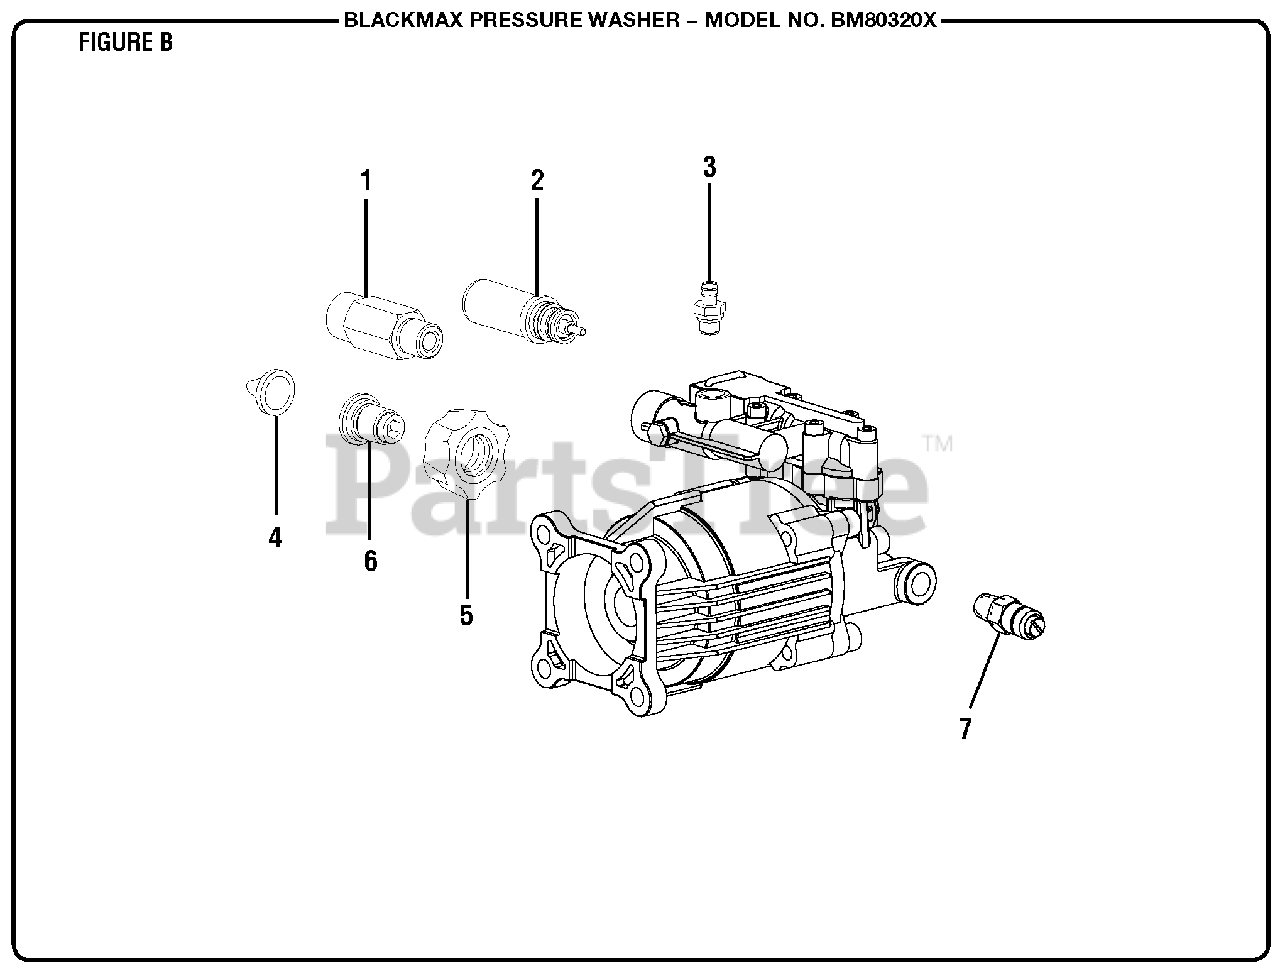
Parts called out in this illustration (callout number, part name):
1	Outlet Tube
2	Unloader Valve Assembly
3	Soap Injector Kit
4	Filter Screen
5	Inlet Filter Adapter/Brass Insert
6	Inlet Filter Connector
7	Thermal Release Valve
